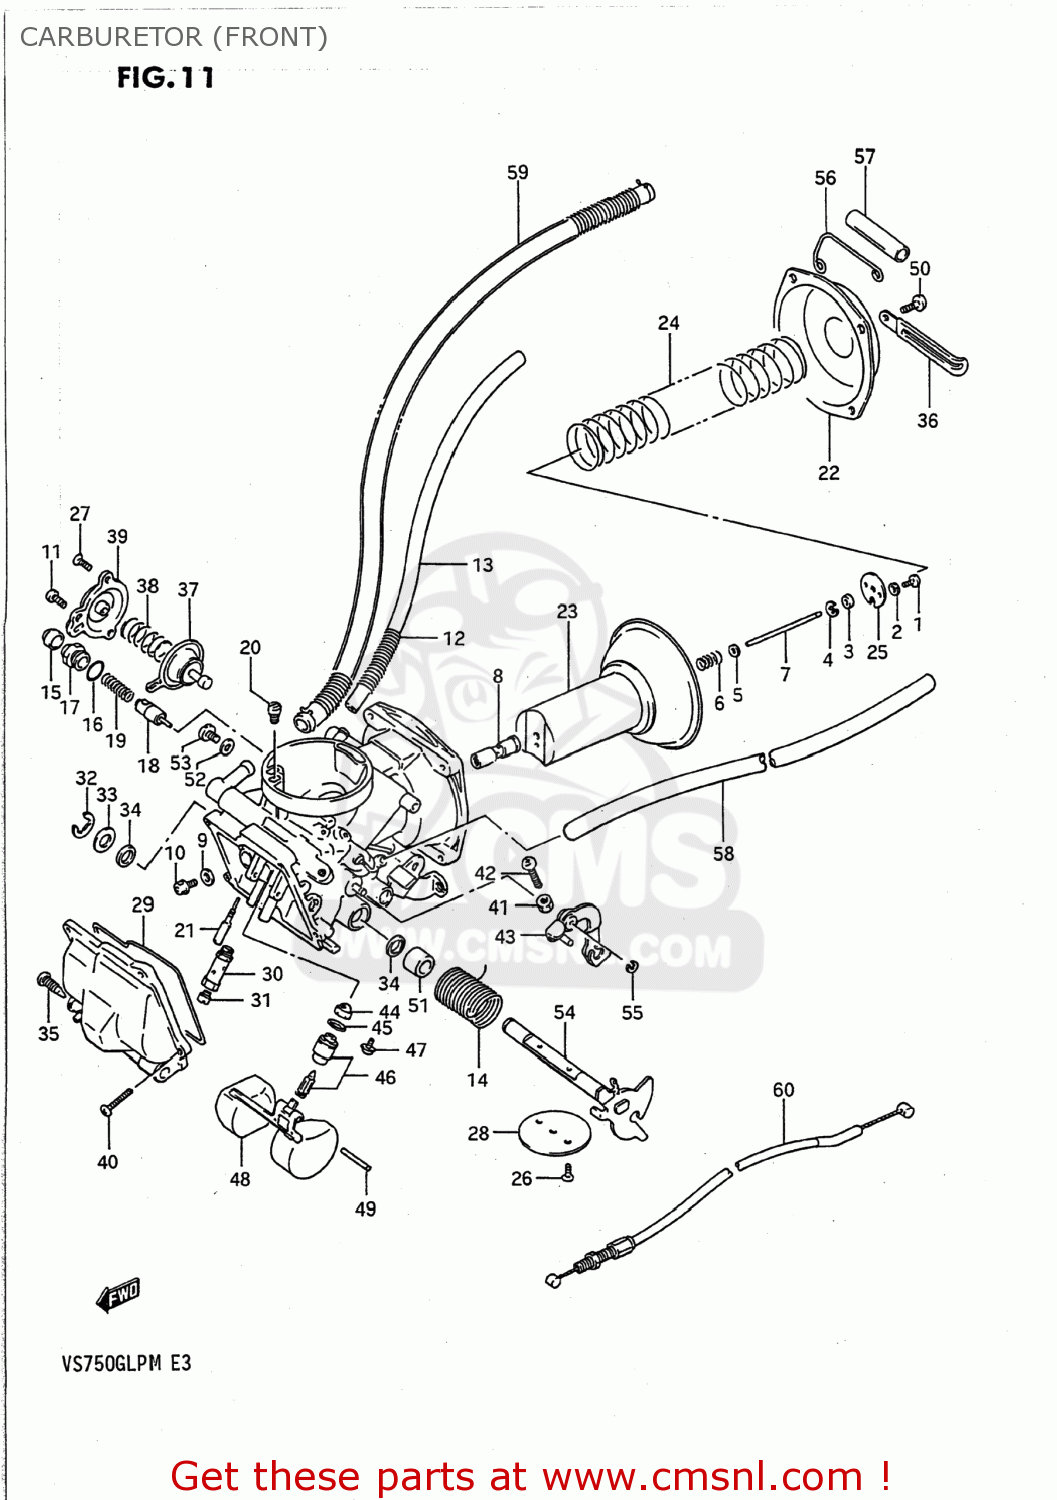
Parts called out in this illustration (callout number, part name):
1	SCREW
2	LOCK WASHER
3	RING
4	CLIP
5	WASHER
6	SPRING
7	NEEDLE JET
8	JET,NEEDLE(P-4)
9	WASHER,NEEDLE NOZZLE
10	SCREW
11	SCREWM4X0.7X10
12	SPRING
13	HOSE
14	SPRING,SHAFT RETURN
15	CAP
16	O RING
17	HOLDER,GUIDE
18	PLUNGER
19	SPRING
20	JET,PILOT(70)
21	JET,PILOT(25)
22	COVER,DIAPHRAGM
23	DIAPHRAGM,CARBURETOR
24	SPRING,DIAPHRAGM
25	PLATE
26	SCREW
27	SCREW
28	VALVE,THROTTLE
29	O RING,FLOAT CHAMBER
30	HOLDER,MAIN JET
31	JET,MAIN (132.5)
32	E RING
33	GASKET,THROTTLE SHAFT (NAS)
34	SEAL,THROTTLE SHAFT
35	PLUG,DRAIN
36	CLAMP L:35
37	DIAPHRAGM ASSY
38	SPRING
39	COVER
40	SCREW
41	NUT
42	SCREW
43	LEVER,ASSEMBLY
44	FILTER
45	O-RING,NEEDLE VALVE
46	VALVE ASSY,NEEDLE
47	SCREW
48	FLOAT
49	PIN,FLOAT
50	SCREW 5X12
51	RING,THROTTLE VALVE
52	WASHER
53	SCREW
54	SHAFT ASSEMBLY,THROTTLE
55	E-RING
56	CLIP
57	HOSE
58	HOSE
59	HOSE ASSEMBLY
60	CABLE,IDLE SYNCRO
